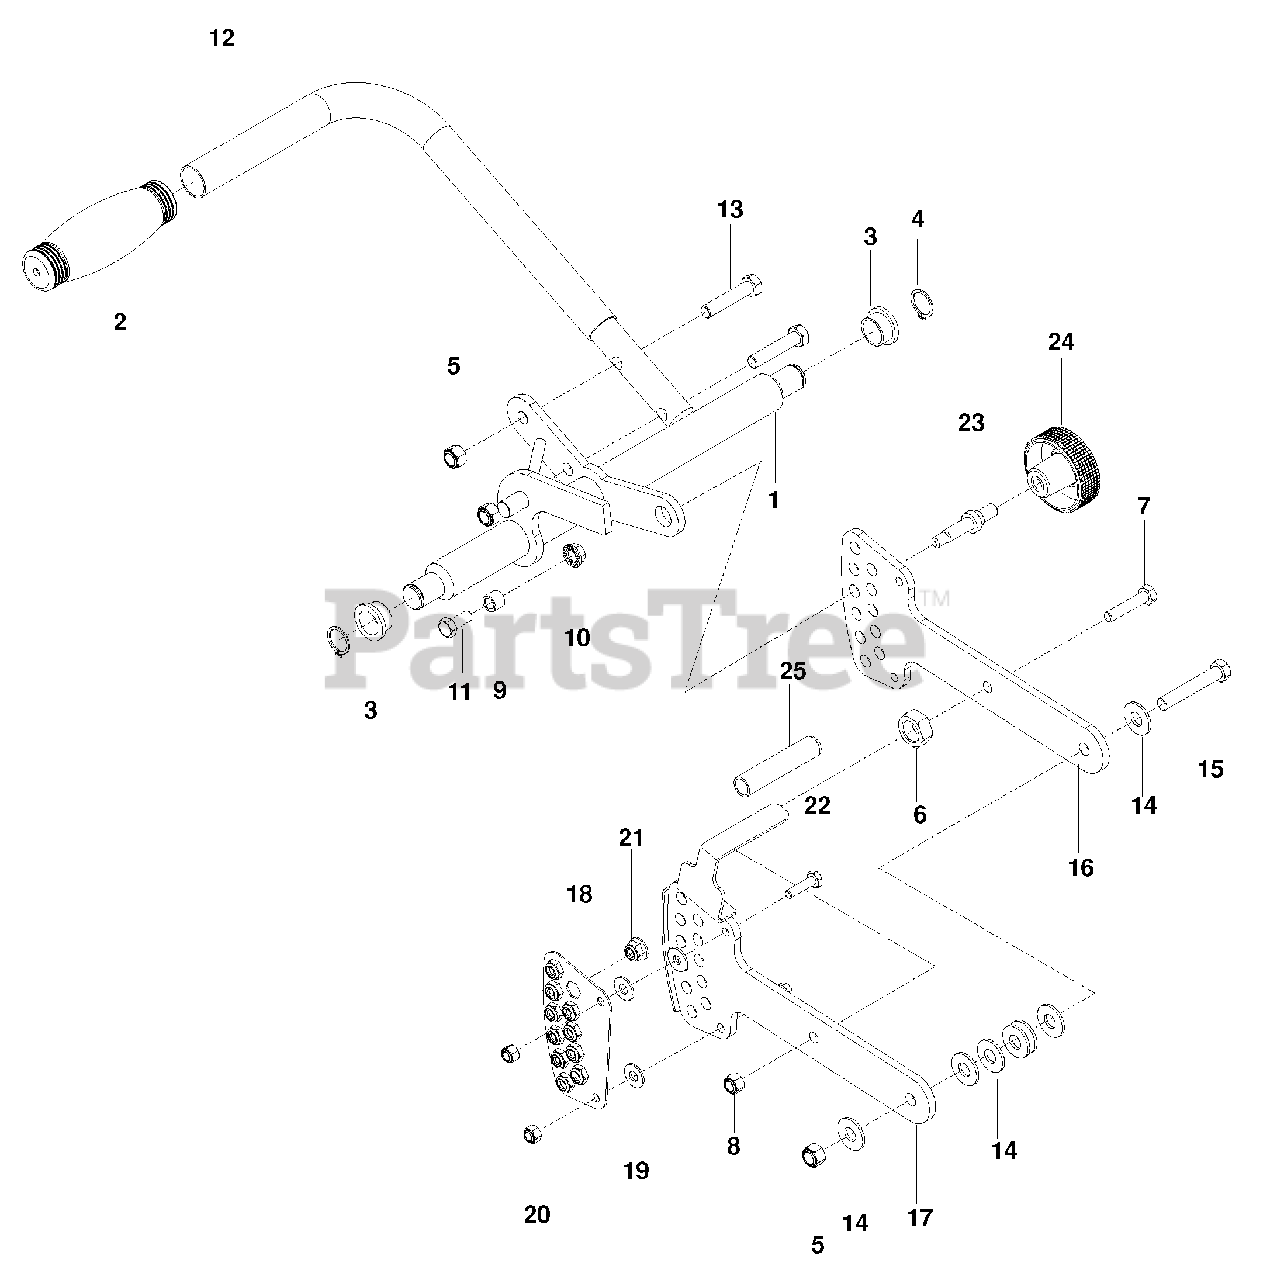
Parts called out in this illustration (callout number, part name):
2	GRIP, HANDLE
3	BEARING, FLANGE
4	SNAP RING 3/4
5	NUT 3/8-16 NYLOC
6	NUT 5/8-18
7	HCS 5/16-18 x 1 1/2
8	NUT 5/16 NYLOC
9	PULLEY SPACER
10	NUT 5/16 WHIZLK
11	HCS 5/16-18 x 3/4
13	HCS 3/8-16 x 1 3/4
14	WASHER 3/8
15	HCS 3/8-16 x 2 1/4
16	ADJUSTER
17	ADJUSTER, RH
18	PLATE-ADJUSTER NUT
19	WASHER 1/4
20	NUT 1/4-20 NYLOC
21	NUT 5/16-18 FLANGE NYLOC
22	HCS 1/4-20 x 1
23	BOLT, STUD ADJUSTER
24	KNOB
25	GRIP, VINYL
